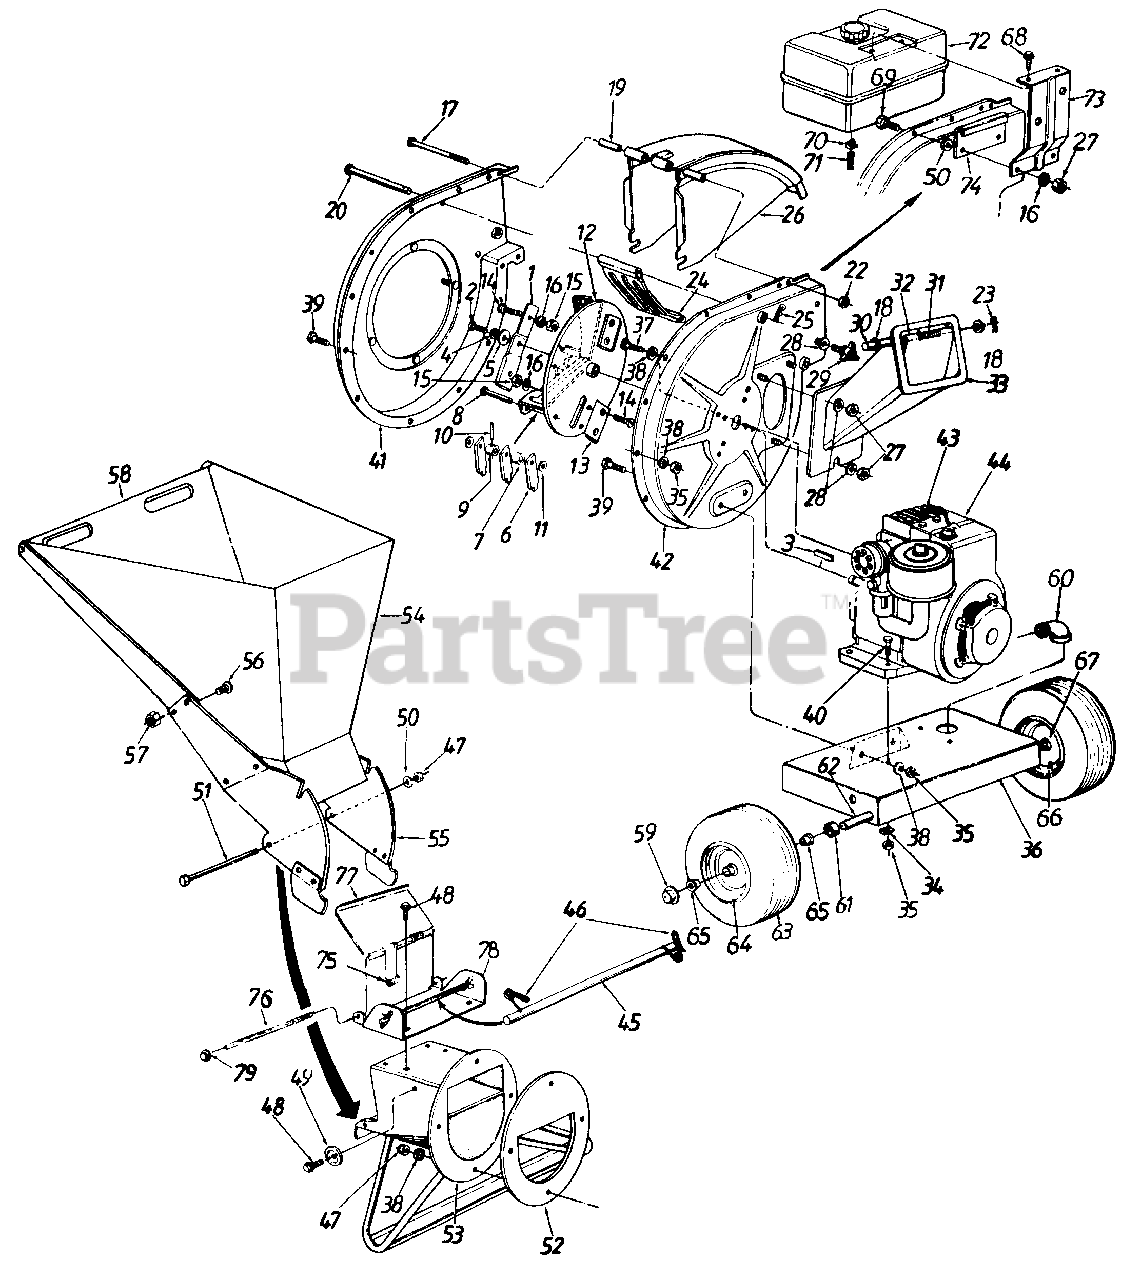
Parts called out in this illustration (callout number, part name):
1	Blade
2	Hex Patch Bolt 3/8-24 x 2" Lg. (Gr. 8)
3	Sq. Key 1/4 x 2.0 Lg.
4	L-Wash. 3/8" I.D. H.D.
5	Fl-Wash. .406" I.D. x 1.25" O.D. Hdn.
6	Flail
7	Flail Spacer
8	Clevis Pin .496" Dia.
9	Flail Spacer w/.160" Dia. Hole
10	Spring Roll Pin 1.12" Lg.
11	Fl-Wash. .531" I.D. x .94" O.D.
12	Impeller Ass'y. Comp.
13	Chipper Blade
14	Flat Hd. Scr. 5/16-24 x .75" Lg.
15	Hex Top L-Nut 5/16-24 (Gr. 5)
16	L-Wash. 5/16" I.D.
17	Hex Bolt 1/4-20 x 3.75" Lg.
18	Fl-Wash. .281" I.D. x .5" O.D.
19	Chute Hinge Spacer 1.66" Lg.
20	Clevis Pin .5" Dia. x 4.62" Lg.
22	Hex Ctr. L-Nut 1/4-20 Thd.
23	Cotter Pin 3/32" x 5/8"
25	Internal Cotter Pin 3/8" Dia.
27	Hex Nut 5/16-18 Thd. (Gr. 5)
28	Bell-Wash. .345" I.D. x .88"
29	Hand Knob
30	Chipper Door Rod
31	Torsion Spring 1.14" Lg.
35	Hex Nut 5/16-18 Thd. (Gr. 5)
38	L-Wash. 5/16" I.D.
39	Hex Bolt 5/16-18 x .75" Lg. Gr. 5)
40	Hex Bolt 5/16-18 x 1.75" Lg.
44	Engine
45	Release Bar
46	Torsion Spring 1.06" Lg.
47	Elastic Lock Nut 5/16-18 Thd.
48	Hex Wash. Hd. Self-Tap Scr. 5/16-18 x .75" Lg.
49	Stop Washer
50	Fl-Wash. 5/16" I.D.
51	Hex Bolt 5/16-18 x 8.38" Lg.
57	Hex L-Nut 1/4-20 Thd.
60	Drain Elbow (5 HP B&S)
61	Spacer .64" I.D. x .38" Lg.
62	Shredder Axle
66	Air Valve
67	Grease Fitting
68	Hex Hi-Low Scr. 1/4 x .75"
69	Hex Bolt 5/16-18 x .88" Lg.
70	Hose Clamp
71	Fuel Line-7 in.
72	Fuel Tank Ass'y. Comp.
76	Hopper Door Rod
